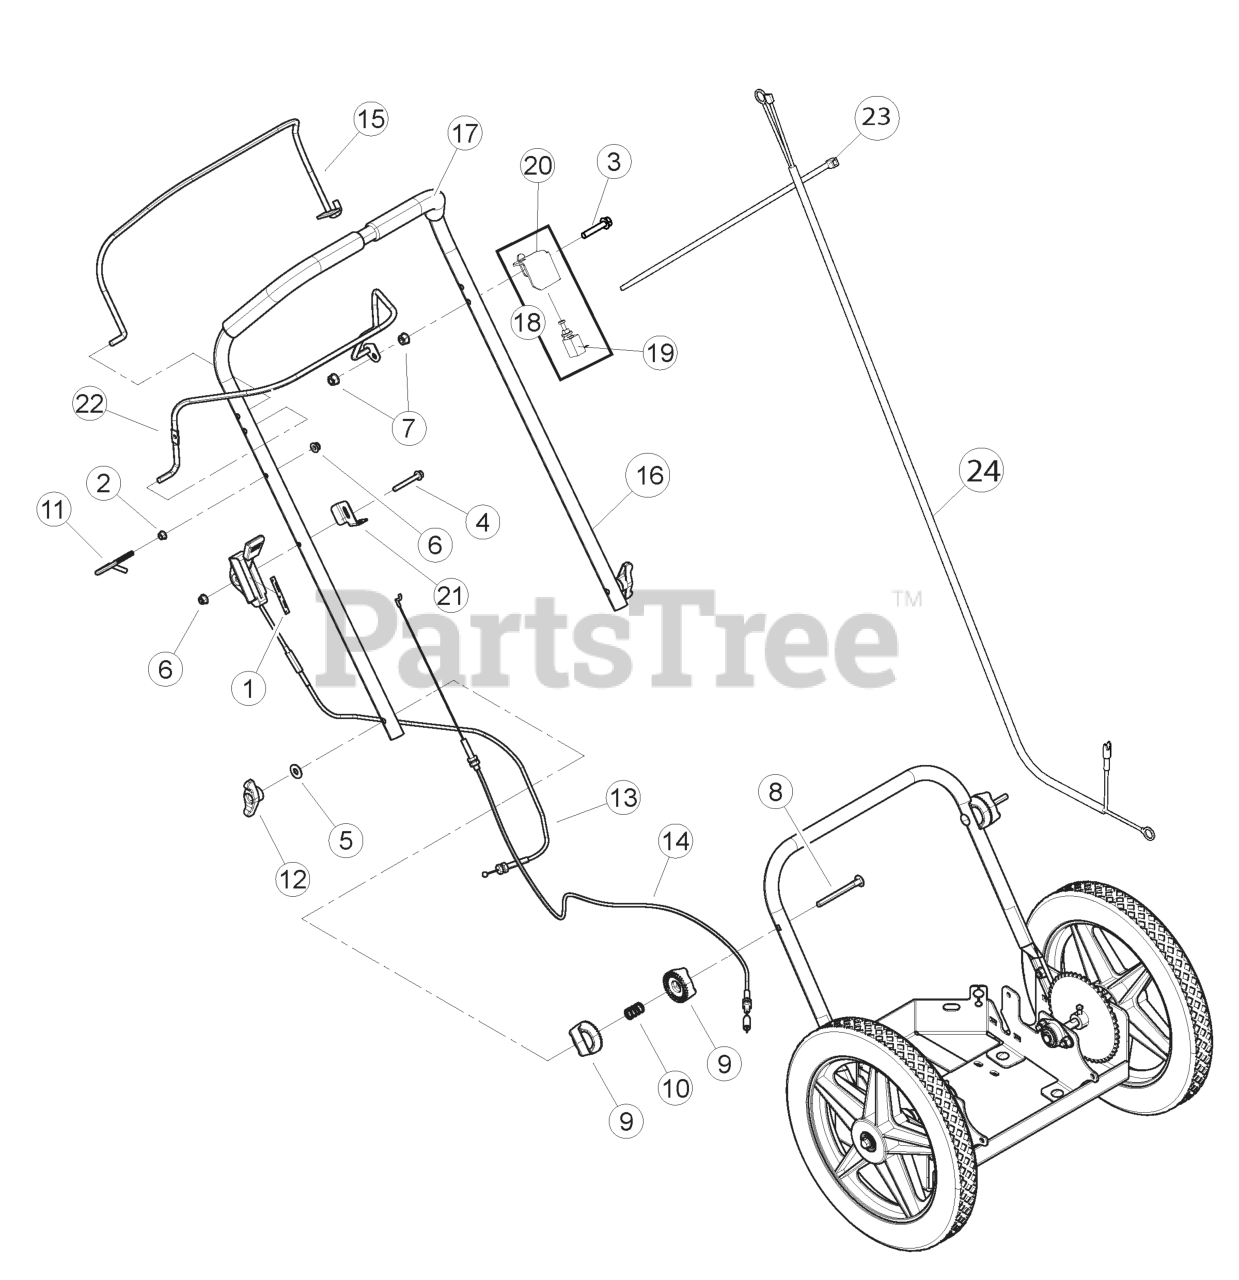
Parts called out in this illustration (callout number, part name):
1	DECAL, 3 SPEED
2	NUT, 1/4"-20 SERRATED FLANGE NC ZP
3	BOLT, 5/16 × 1-3/4 FLANGE NC
4	BOLT, 1/4 × 2 FLANGE NC
5	WASHER, 5/16 FLAT
6	NUT, 1/4-20 NYLOCK-FLANGE
7	NUT, 5/16-18 NYLOCK FLANGE
8	BOLT, 5/16-18 × 3-1/2 LONG NECK GR5 CRG ZP
9	RETAINER, HANDLE BAR ADJUSTMENT
10	SPRING, RETAINER COMPRESSION
11	GUIDE, RECOIL ROPE
12	KNOB, 5/16-18 FEEM TEE
13	CABLE, 3 SPEED WT
14	CABLE, TRANS ENGAGE WT
15	ASSEMBLY, BAIL HW TRIMMERS
16	ASSEMBLY, UPPER HANDLE BAR WITH GRIPS
17	PAD, FOAM HANDLE BAR
18	SWITCH KIT,BRACKET AND KILL
19	SWITCH, ENGINE KILL
20	BRACKET, WT KILL SWITCH
21	BRACKET, WT ENGAGE CABLE
22	ASSEMBLY, BAIL WT TRIMMERS
23	STRAP, 11 IN BLACK TIE
24	HARNESS, BRIGGS HW KILL SWITCH
